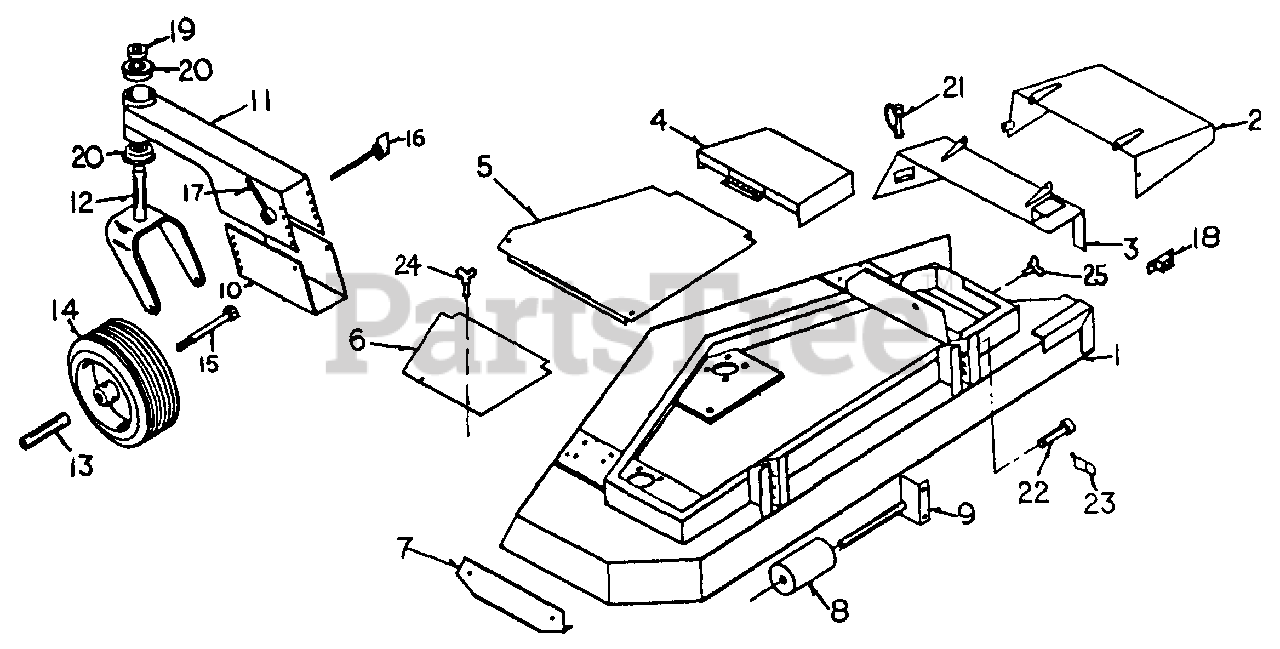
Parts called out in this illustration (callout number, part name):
3	Foot Guard Mount
8	Anti-scalp Roller
9	Shaft & Bracket
10	Gauge Wheel Mount Bracket
11	Gauge Wheel Mount
13	Axle
14	Gauge Wheel Assembly
15	Hex Bolt, 1/4-20 x 4 1/2", GR5
18	10 Amp Circuit Breaker
19	Set Collar, 1"
23	Hair Pin Cotter
24	Thumb Screw, 1/4-20 x 1/2"
25	Wing Screw, 1/2-20 x 1"
